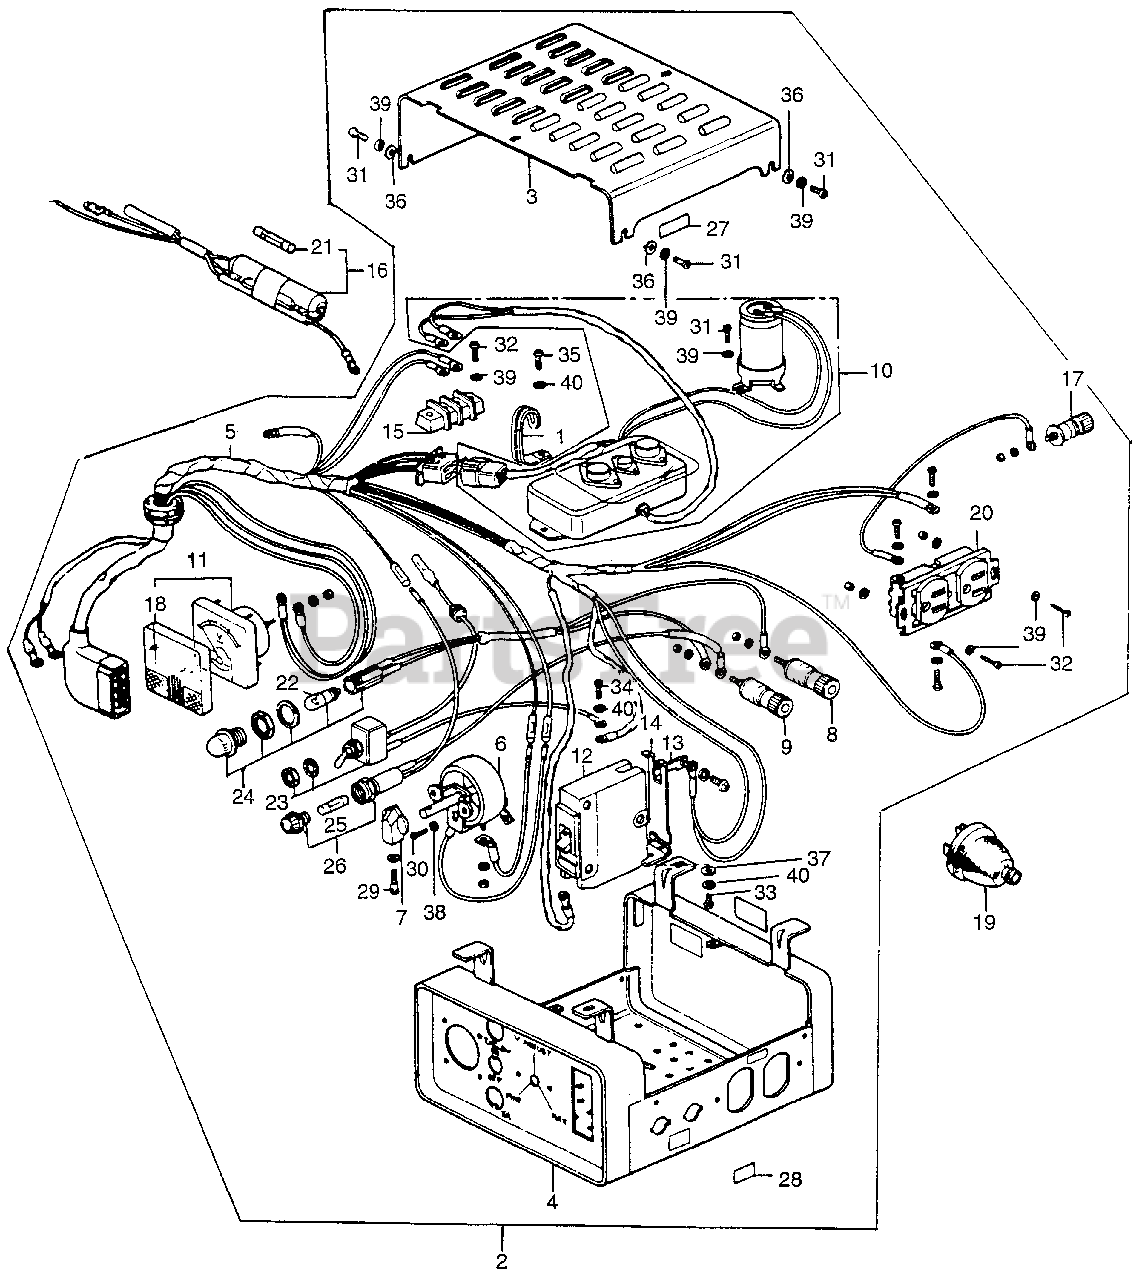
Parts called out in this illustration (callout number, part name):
1	CLAMP B, WIRE
2	BOX ASSY., CONTROL *R8* (BRIGHT RED)
3	COVER, CONTROL BOX (UPPER) *R8* (BRIGHT RED)
4	COVER, CONTROL BOX (LOWER) *R8* (BRIGHT RED)
5	WIRE HARNESS ASSY. (NOT AVAILABLE)
6	RESISTOR, VARIABLE (NOT AVAILABLE)
7	KNOB, ADJUSTING
8	TERMINAL, D.C. OUT (+)
9	TERMINAL, D.C. OUT (-)
10	REGULATOR ASSY., AUTOMATIC VOLTAGE (NOT AVAILABLE)
11	VOLTMETER ASSY.
12	BREAKER, CIRCUIT (25A) (NOT AVAILABLE)
13	TERMINAL, BREAKER
14	SUPPORT, BREAKER (NOT AVAILABLE)
15	TERMINAL (2 POLE)
16	FUSE DIODE
17	TERMINAL ASSY., GROUND (NOT AVAILABLE)
18	LENS, METER (NOT AVAILABLE)
19	PLUG ASSY., RECEPTACLE
20	RECEPTACLE (15A-125V)
21	FUSE (2.5A)
22	BULB (24V2W)
23	SWITCH ASSY., ENGINE (NOT AVAILABLE)
24	SOCKET ASSY., PILOT LAMP (NOT AVAILABLE)
25	FUSE (15A)
26	HOLDER ASSY., FUSE
27	MARK C, CAUTION (NOT AVAILABLE)
28	MARK B, D.C. OUTPUT
29	BOLT, KNOB (NOT AVAILABLE)
30	SCREW, PAN (3X6)
31	SCREW, PAN (4X6)
32	SCREW, PAN (4X12)
33	SCREW, PAN (5X8)
34	SCREW, PAN (5X8)
35	SCREW, PAN (5X10)
36	WASHER, PLAIN (4MM)
37	WASHER, PLAIN (5MM)
38	WASHER, SPRING (3MM)
39	WASHER, SPRING (4MM)
40	WASHER, SPRING (5MM)
